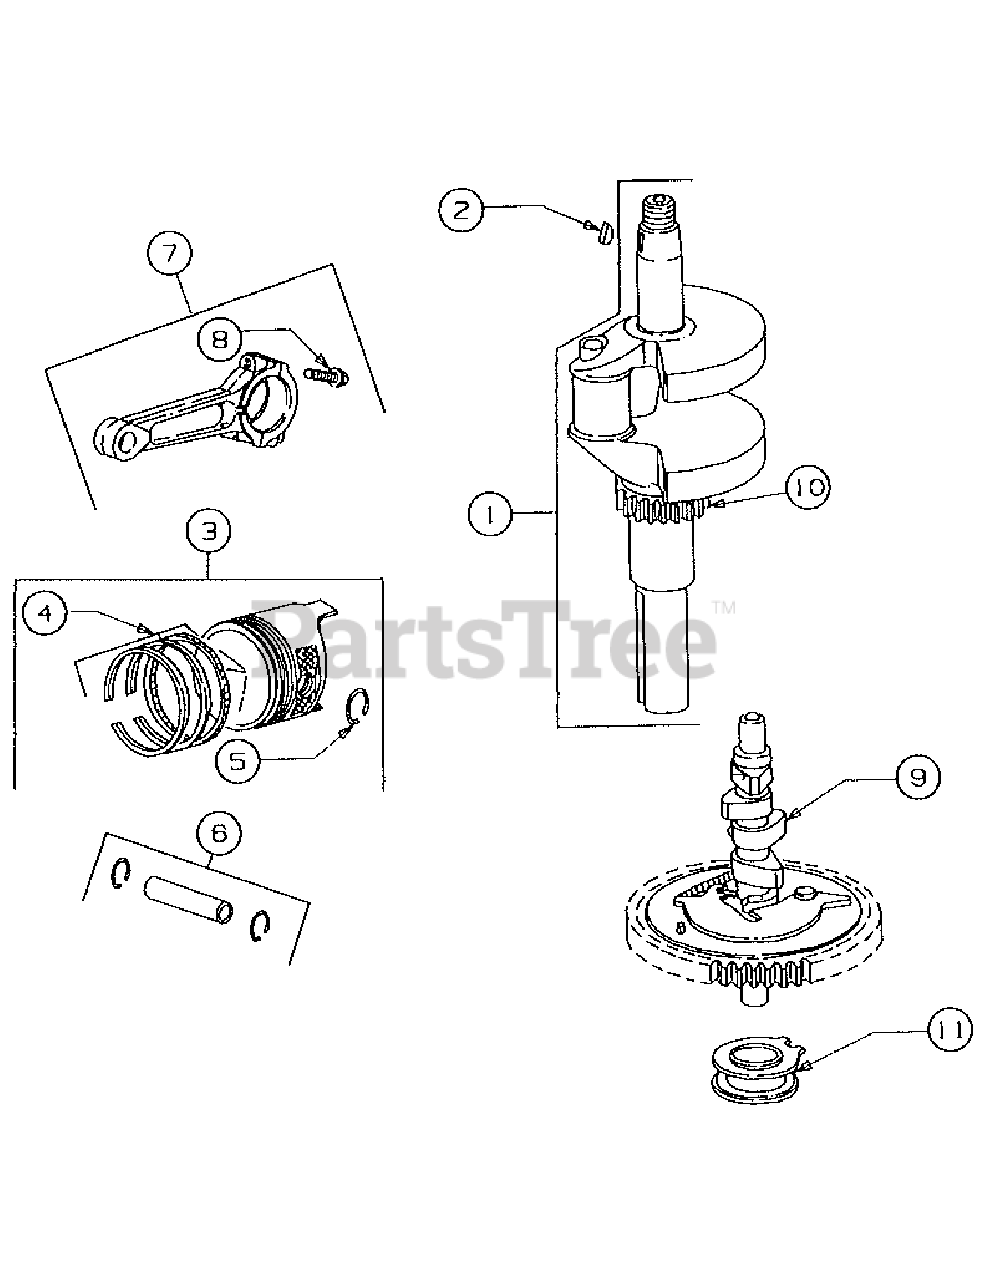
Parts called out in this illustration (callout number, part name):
1	Crankshaft
2	Key, Flywheel
3	Piston Assembly
4	Ring Set, Piston
5	Lock, Piston Pin
6	Piston Pin Assembly
7	Rod Assembly, Connecting
7	Rod, Connecting
8	Screw, Connecting Rod
9	Gear, Cam
10	Gear, Timing
10	Key, Timing Gear
11	Slider, Governor
